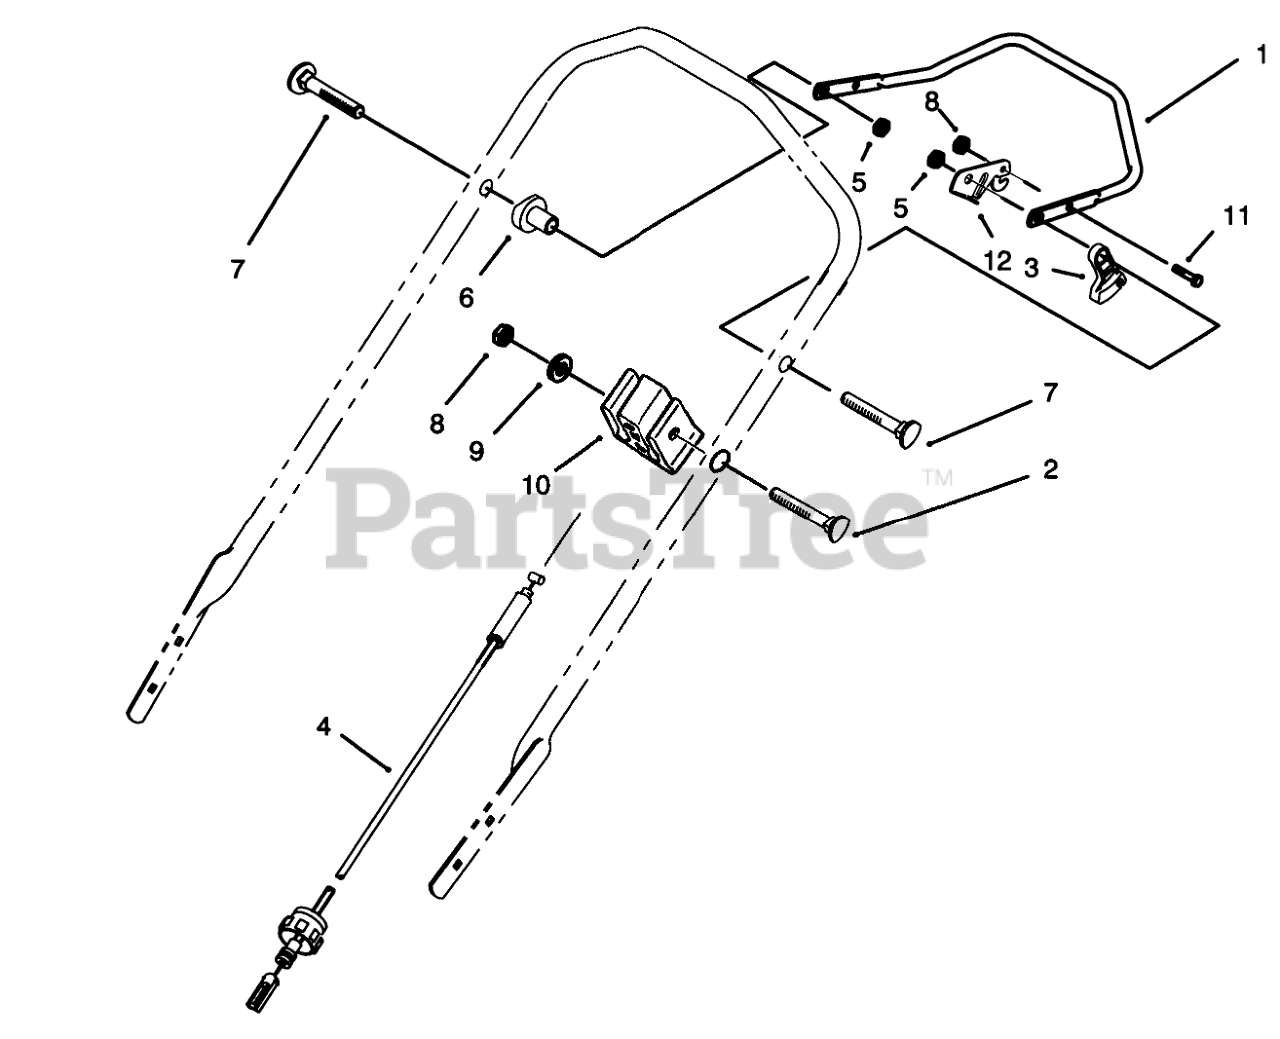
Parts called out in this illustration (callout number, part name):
1	Bar-Control
2	HANDLE SCREW
3	LEVER-TRACTION
4	CABLE-TRACTION
5	NUT-LOCK, NI
6	SPACER-SUPPORT
7	5/16-18 X 2 HNDLE SCREW
8	NUT-LOCK, NI
9	WASHER-FLAT
10	SUPPORT-CABLE
11	SCREW-HH
12	CONTROL LEVER
